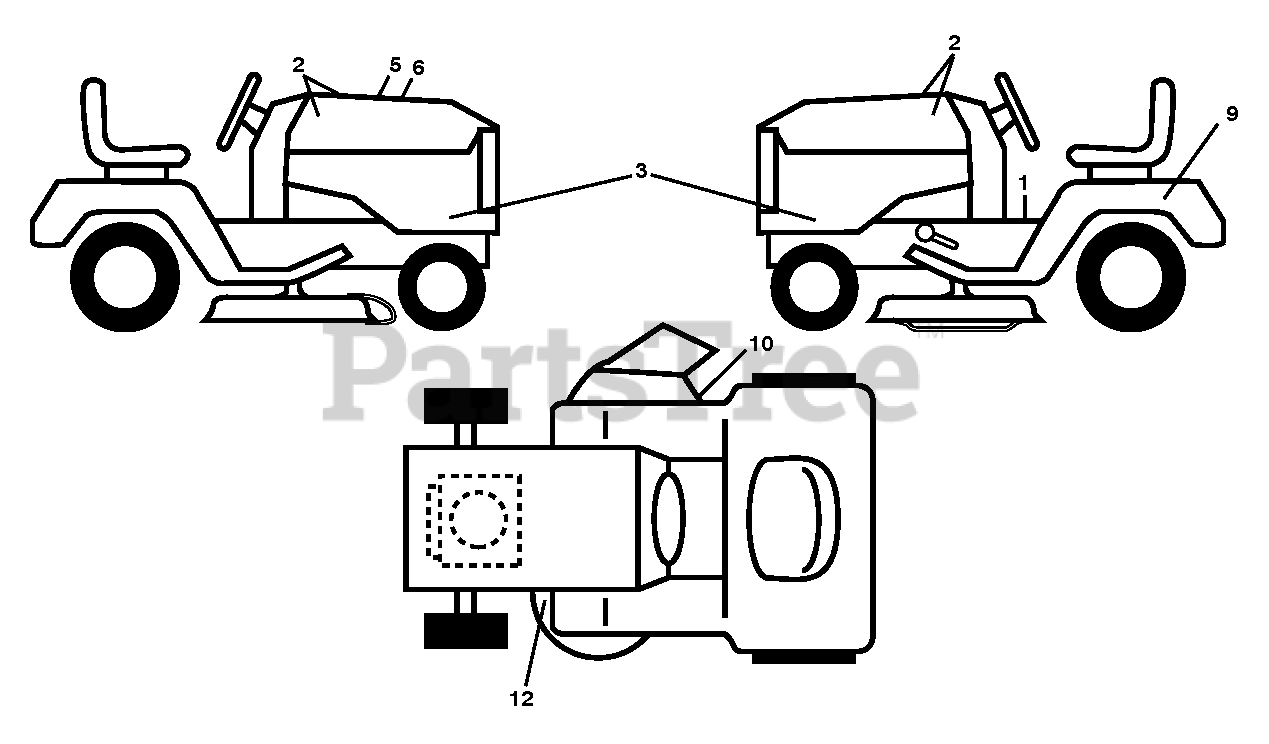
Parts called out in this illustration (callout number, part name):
1	DECAL.FENDER.WARNING.ENGLISH
2	DECAL.BADGE.170MM.TEXTLOGO.
3	Decal, Side Panel YTH20K46 Set
5	DECAL.WARNING.CUST.RESP.E85.
9	DECAL BTRY SYMBOLS
10	DECAL.MOWER.WARN.KEEP.HAND.AWY
12	DECAL.V-BELT.SCH.42/46"MEC/ELE
